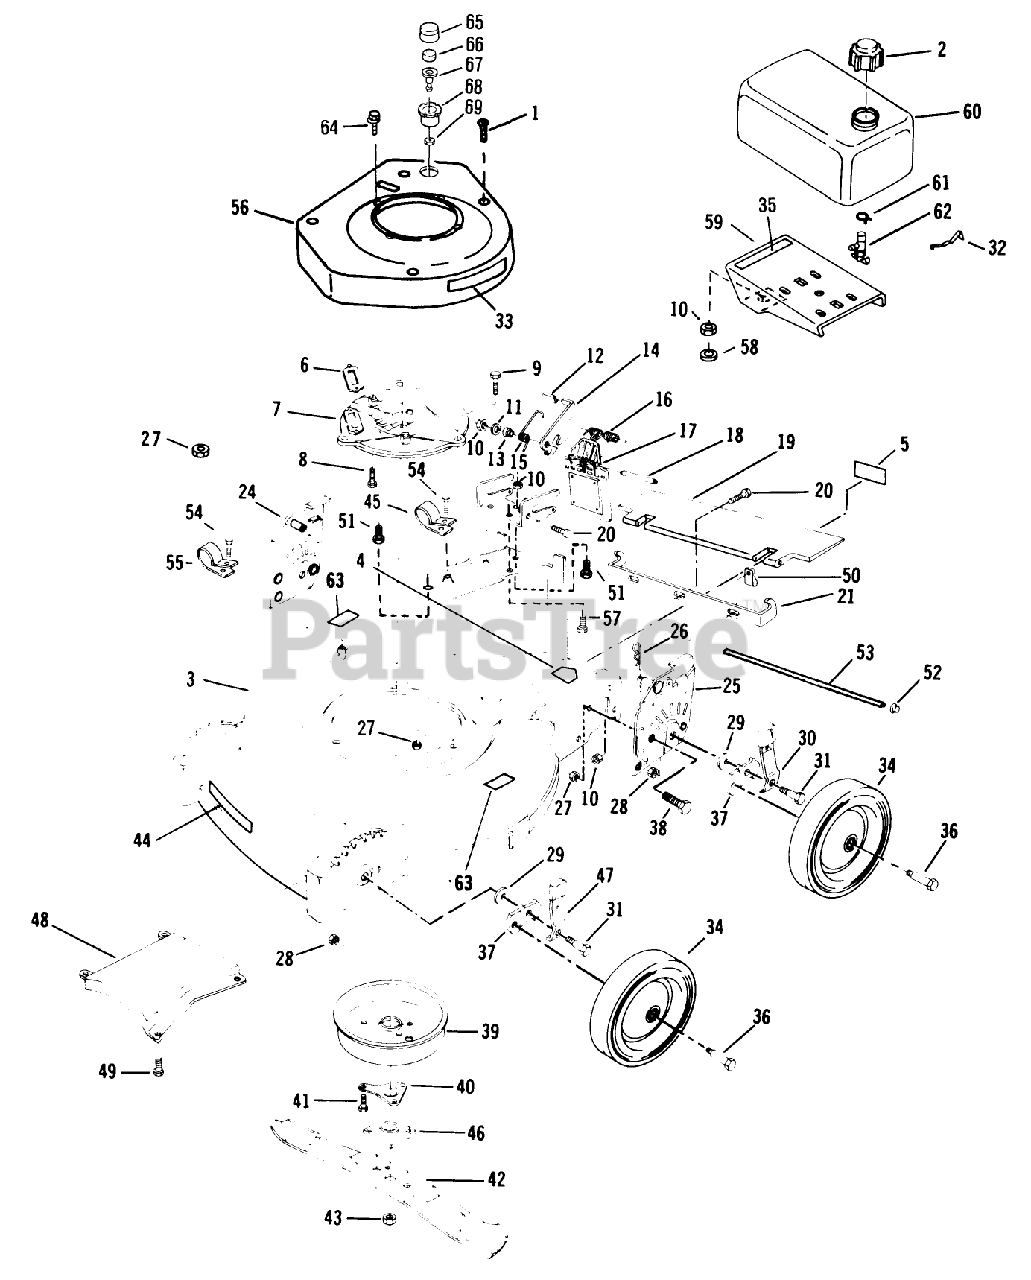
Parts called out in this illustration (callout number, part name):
1	SCREW - SELF TAPPING
2	FUEL CAP & INSERT
7	PLATE F
8	SCREW V
9	SCREW-HH
10	LOCKNUT E
15	SPRING
16	SPRING ASOC
18	ROD (RB&W)
19	T/SHIELD SM&P
26	HAIR PIN
27	NUT-LOCK F
28	LOCKNUT
29	WASHER
31	BOLT
32	SPRING
34	WHEEL & TIRE
36	BOLT-SHOULDER
39	MUFFLER COVER F
40	SUPPORT F
41	SCREW
43	NUT-BLADE
46	PLATE AND COLLAR ASM
48	BAFFLE CHUTE PL
51	SCREW HEX WASHER
54	SCREW LAWRENCE
57	SCREW
58	WASHER
61	CLAMP - HOSE S
62	VALVE&SCREEN SM
64	SCREW SEMS SM
66	FILTER S
67	BASE P'MERBULB S
68	CUP PRIMER S
